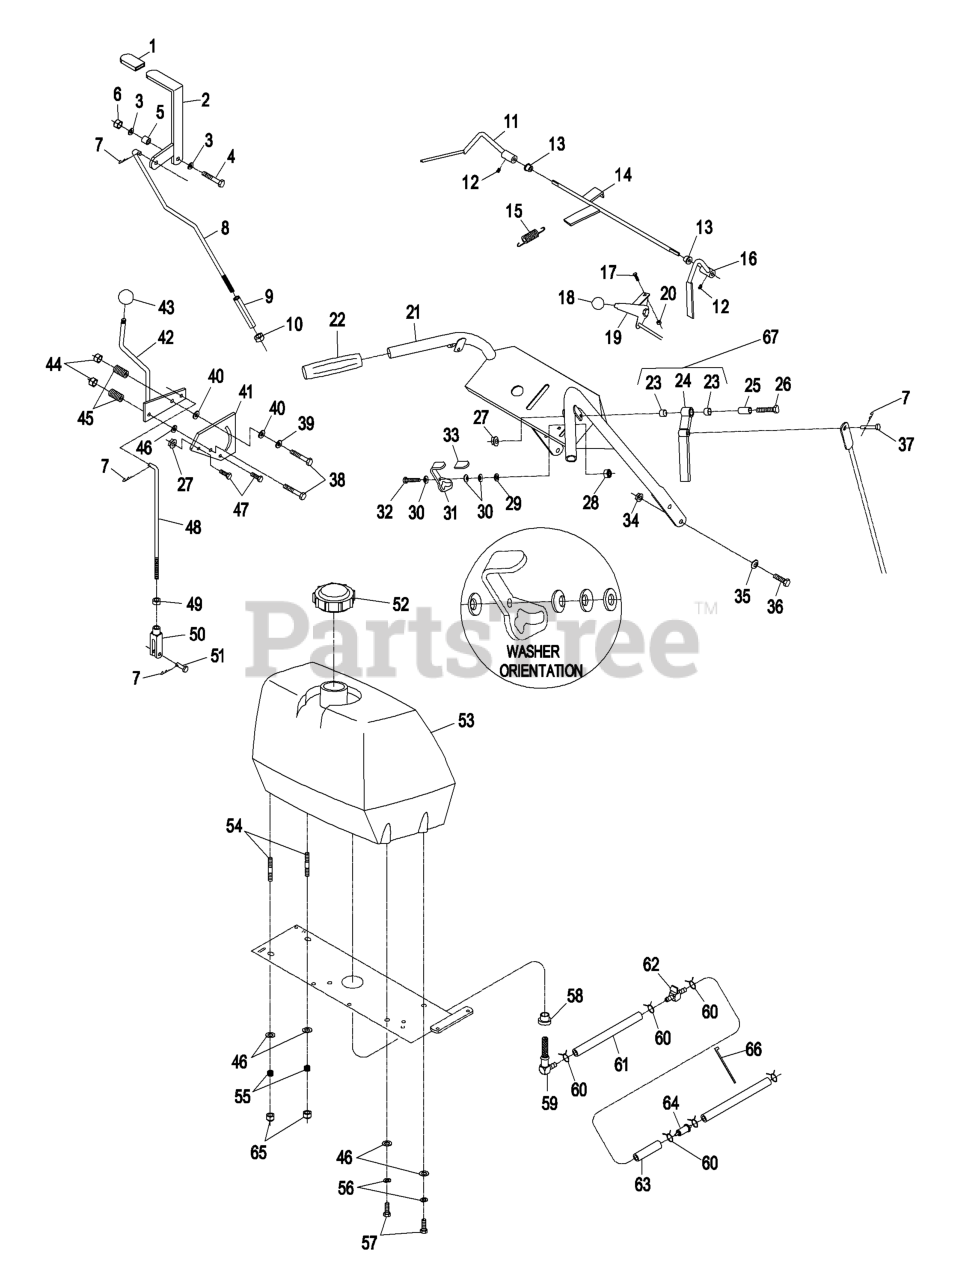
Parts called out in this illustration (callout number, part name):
1	GRIP-LEVER
3	WASHER-FLAT
4	SCREW-HH
5	BUSHING-LEVER, LIFT
6	NUT-LOCK, NI
7	PIN-COTTER
8	LINKAGE,UPPER
9	TURNBUCKLE
10	NUT-HEX
11	LEVER-LH
12	SCREW-SET
13	BUSHING-NYLON
14	WLD,ROD OPC
15	SPRING-EXTENSION
16	LEVER-RH
17	BOLT-CARR
18	KNOB-BALL
19	CONTROL,THROTTLE
20	NUT-LOCK, NI
21	KIT,HANDLE/DECALS TTHP
23	BUSHING-SLEEVE
25	BUSHING-LEVER, DRIVE
26	SCREW-HH
28	NUT-LOCK, NI
29	WASHER-FLAT
30	WASHER-SPRING
32	SCREW-HH
33	GRIP-LATCH
34	NUT-HHF, WHIZ
35	WASHER-BELLEVILLE
36	SCREW-HH
37	PIN-CLEVIS
38	SCREW-HH
39	WASHER-FRICTION
40	WASHER-FRICTION
41	PLATE-LEVER, SHIFTER
43	KNOB-BALL
44	NUT-LOCK, NI
45	SPRING-COMPRESSION
46	WASHER-PLAIN
47	SCREW-HH
48	ROD,SPEED CONTROL
49	NUT-JAM
50	YOKE-ADJUSTABLE
51	PIN-CLEVIS
52	CAP-FUEL
54	STUD
55	SPRING-TANK, FUEL
56	WASHER-LOCK
57	SCREW-HH
59	ELBOW-TANK, FUEL
61	HOSE-FUEL
62	VALVE-FUEL
63	HOSE-FUEL
64	Kawasaki Pn 41019-1055
65	NUT-LOCK, NI
66	TIE-PLASTIC
67	RH DRIVE LEVER ASM
